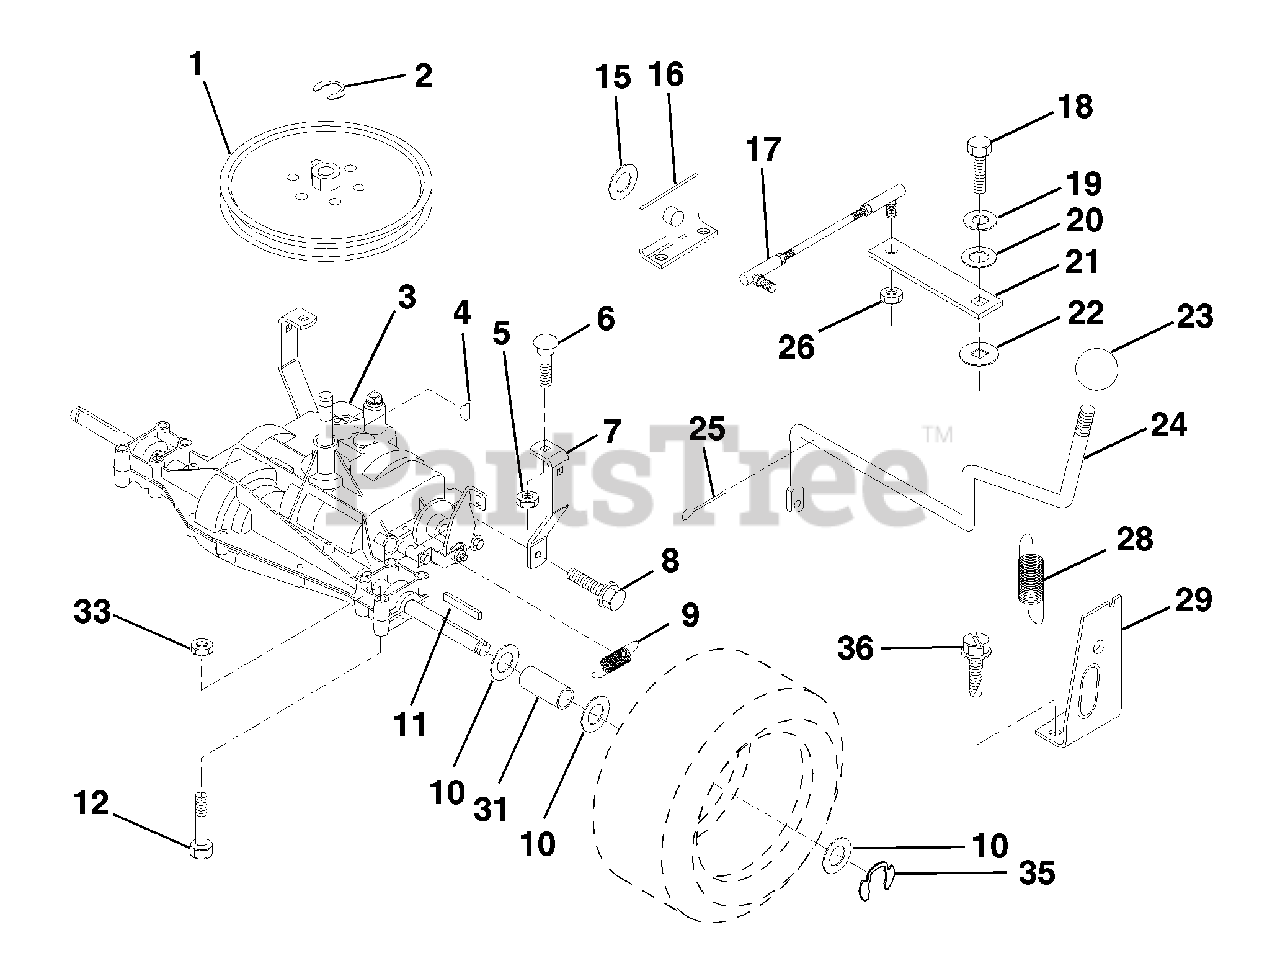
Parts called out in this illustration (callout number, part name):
2	Ring, Retainer
3	Dana Transaxle
4	Key, Woodruff #9
5	Nut, Crownlock 5/16-18
6	Bolt, Carriage 5/16-18 UNC x 3/4
7	Strap, Torque
8	Screw 5/16-18 x 3/4
9	Spring, Brake
10	Washer 25/32 x 1-1/4 x 16 Ga.
11	Key, Square
12	Bolt, Hex Hd 3/8-16 UNC x 2-3/4
15	Washer 17/32 x 1 x 16 Ga.
16	Support Handle Shift LH
17	Link, Shift
18	Bolt, Fin Hex 1/4-28 UNF x 3/4 Gr. 8
19	Washer, Lock 1/4
20	Washer 9/32 x 3/4 x 10 Ga.
21	Arm, Shift
22	Washer, Shift Plate
23	Knob, Rd 1/2-13
25	Pin, Cotter 1/8 x 1
26	Locknut 5/16-24 UNF
28	Extension, Spring
29	Support Handle Shift RH
31	Spacer Axle
32	Washer 11/32 x 11/16 x 16
33	Nut, Hex Crownlock 3/8-16
36	Screw, Thd Cut 1/4-20 x 1/2
